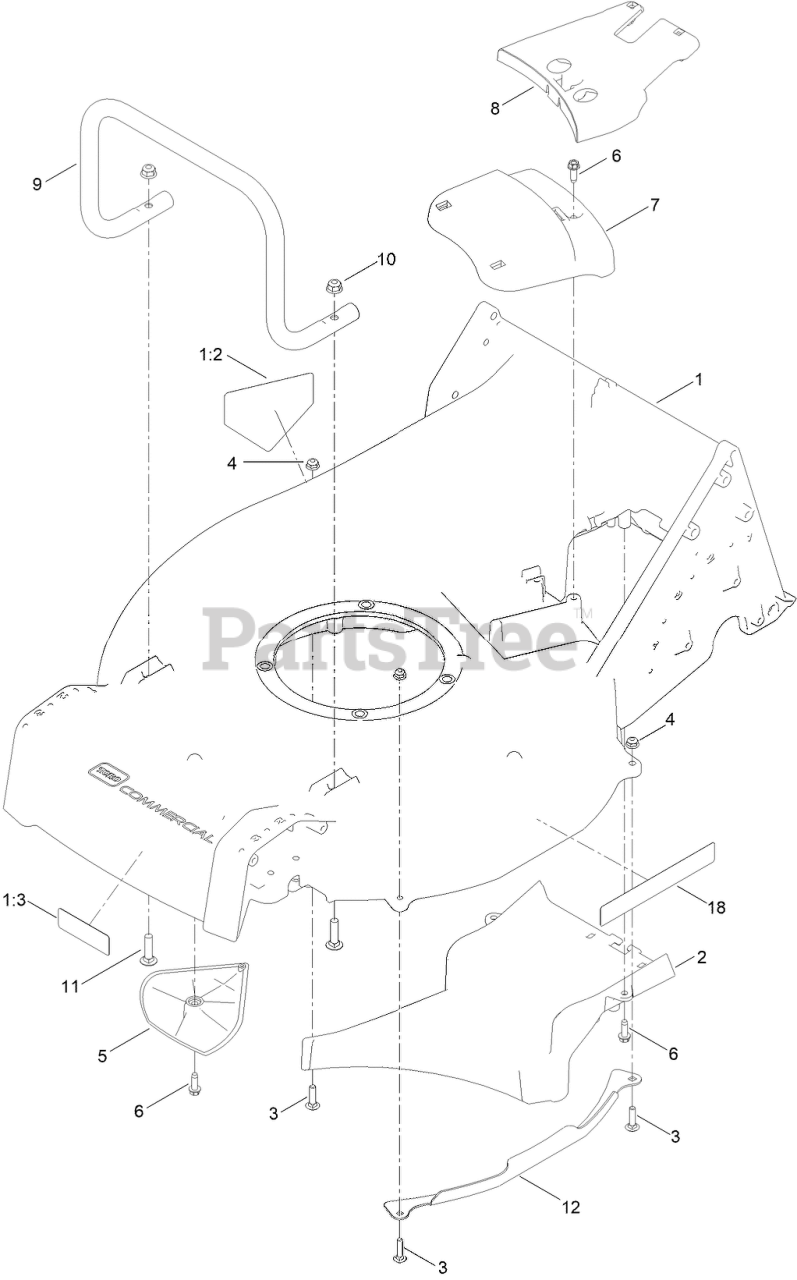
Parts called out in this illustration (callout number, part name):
1	HOUSING ASM
1:2	DECAL-DANGER
1:3	DECAL-WARNING, BLADE
2	FLOOR-CHUTE
3	SCREW-CARR
4	NUT-HF
5	KICKER
6	SCREW-HWHTF
7	COVER-BELT, FRONT
8	COVER-BELT, REAR
9	GUARD-ENGINE
10	NUT-HF, NI
11	SCREW-CARR
12	GUARD-SIDE, DECK
18	DECAL-RECYCLER
